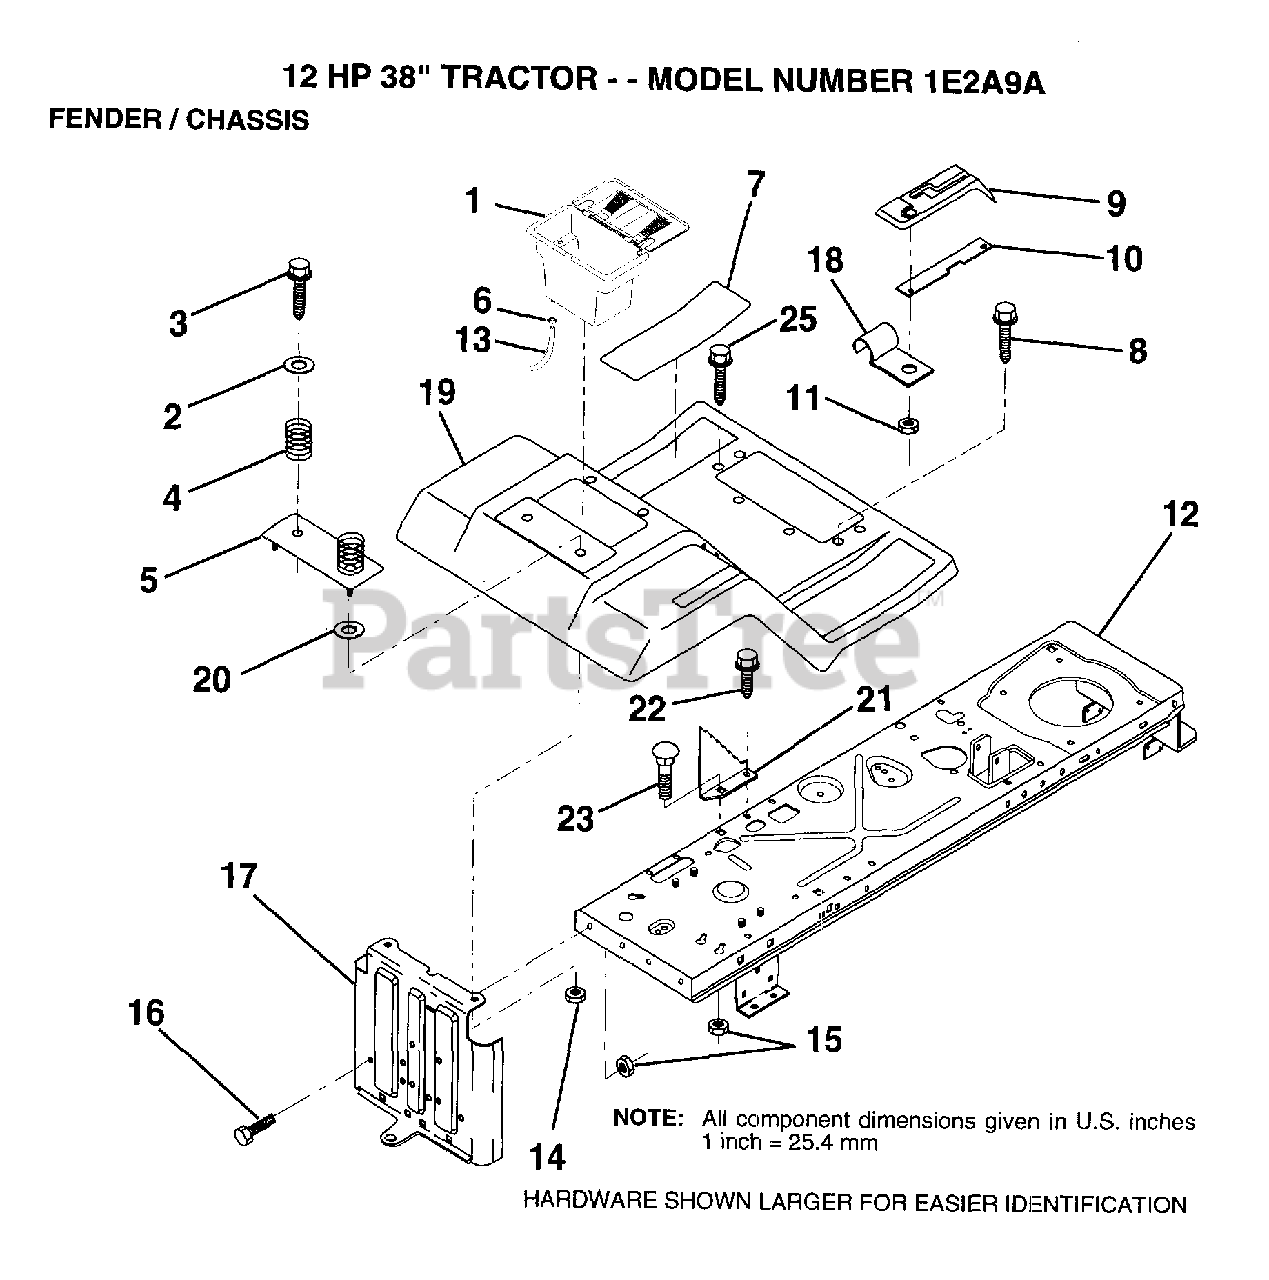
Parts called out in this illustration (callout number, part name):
2	WASHER
3	SCREW
4	SPRING COMPRESSIO
5	BTRY FENDER PLATE
6	HOSE CLAMP T
7	PAD FOOTREST
8	SCREW
10	"SHIFT LOCK, BAR"
11	NUT
13	TUBE T
14	NUT
16	BOLT
17	DRAWBAR
18	"CLIP,INSULATOR"
22	SCREW LT
25	SCREW TI
